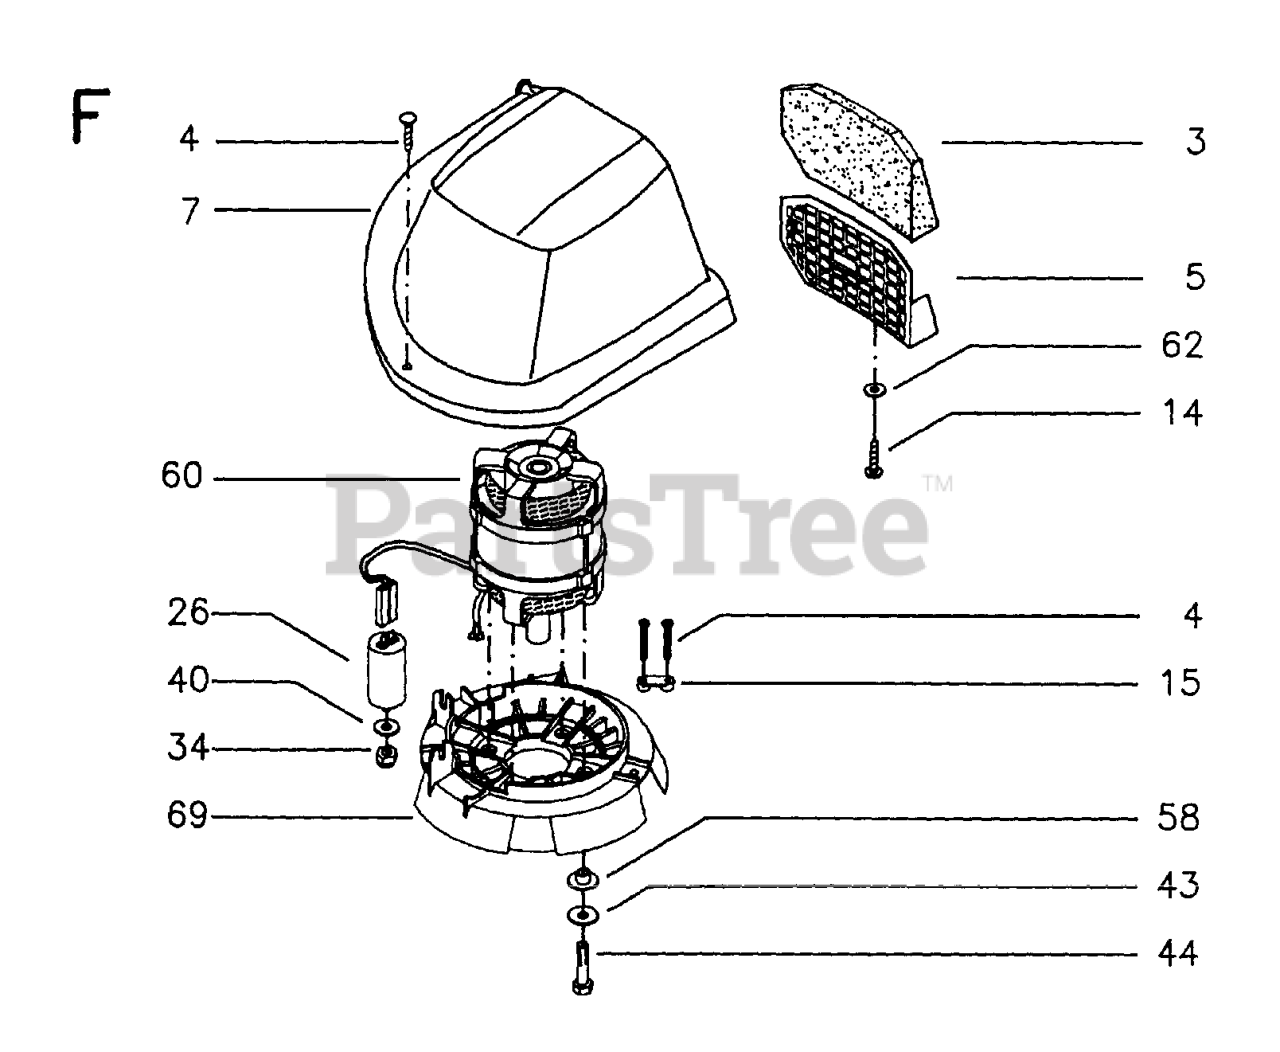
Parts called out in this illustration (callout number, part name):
15	CABLE CLAMP
34	NUT
40	WASHER - 15X7.3X1.6
58	FLANGE BRG.
69	REPL BY 517 77 03-23
